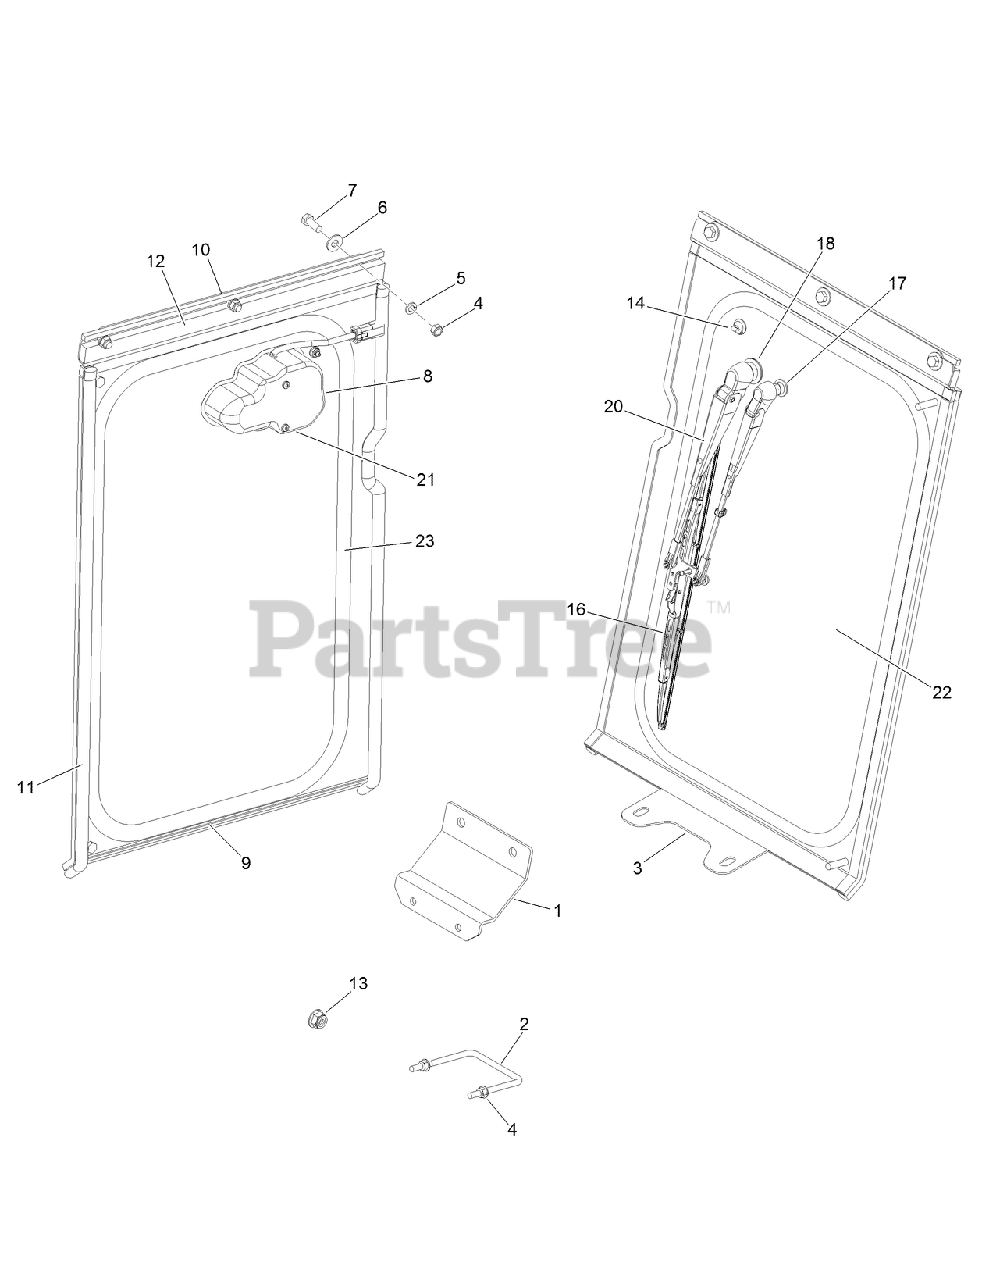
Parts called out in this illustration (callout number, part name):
1	MOUNT-BRACKET, MUFFLER
2	U-BOLT
3	MOUNT-PANEL, WINDSHIELD
4	NUT-HEX
5	WASHER-LOCK
6	WASHER-FLAT
7	BOLT-HHCS
8	BOLT-HHCS
9	SEAL-RUBBER
11	SEAL-RUBBER
12	SEAL-RUBBER
13	NUT-HEX
14	FITTING-HOSE, WIPER
16	BLADE-WIPER
17	M8 MOUNT HARDWARE
18	M16 MOUNT HARDWARE
20	WIPER-ARM
21	MOTOR-WIPER
22	GLASS-WINDSHIELD
23	RUBBER-WINDOW
